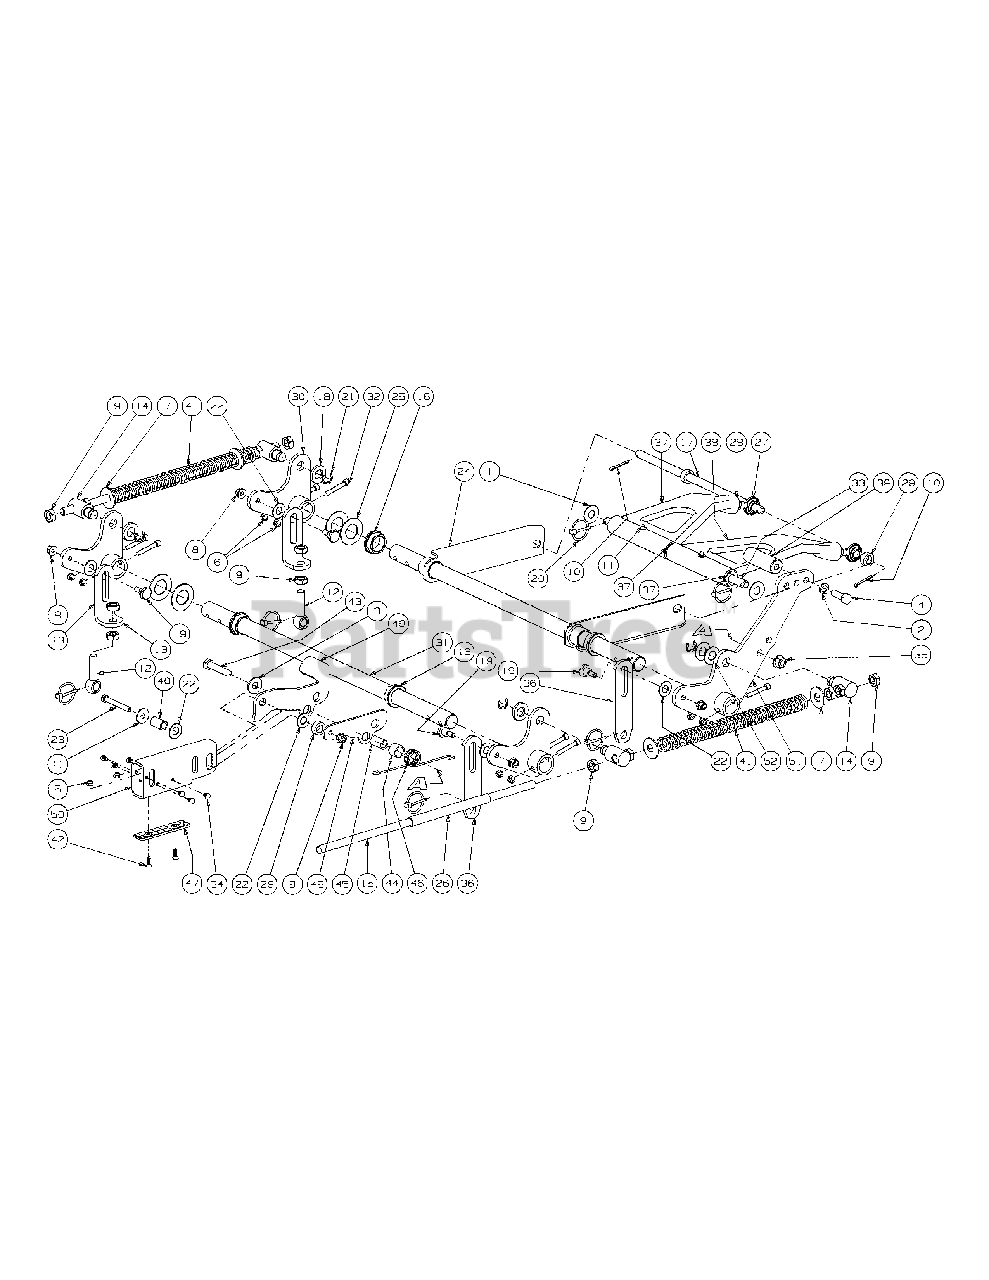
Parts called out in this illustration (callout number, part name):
1	Washer, 1.5 x .655 x .055
2	Lock Washer, 1/2
3	Flat Washer, .536 ID x .930 OD x .05
4	Hex Cap Screw, 1/2-13 x 1.50
5	Lock Nut w/Nylon Insert
6	Nut, 5/16-18, Nylock
7	Flat Washer, 5/8
8	Hex Nut, Flange Lock, 3/8-16
9	Jam Nut, 5/8-11
10	Cotter Pin, 3/16 x 1-1
11	Flat Washer, 1.25 x .411 x .100
12	Eye Bolt, 5/8ID
13	Eye Bolt Mount Link, 5/8 ID
14	Ferule Lift
15	Lift Connector Rod
16	Hex Flange Bearing, 1.25 ID
17	Front Lift Link, Rod Mount
18	Spacer, .812 ID x .268 Lg.
19	Shoulder Screw, 0.625 OD x .437 Lg.
20	Linch Pin, 3/16 Dia.
21	E Clip, 3/4 Dia.
22	Nylon Flat Washer, 5/8
23	HHCS, 3/8-16, 3.00
24	Front Frame Strut Assembly
25	Flat Washer, 1.25 ID
26	Hose, 5/8 ID 13/16 OD, 8" LG
27	Rod End, Male
28	Jam Nut, 5/8-18
29	Spacer, .630 ID x 1.06 OD x .440
30	Bellecrank Weldment Assembly
31	Deck Lift Shaft
32	Socket Head CapScrew, 5/16-18 x 2
33	Lift Link Rod
34	Rivet, 1/4 x 5/8
35	Nut, 1/2-13, FlangeLock
37	Bearing Lift Brace Assembly, Left Hand includes:
37	Grease Fitting
38	Bearing Lift Brace Assembly, Right Hand includes:
38	Grease Fitting
39	Deck Lift Foot Pedal
40	Spacer, .375 ID x .625 OD x 2.20
41	Lift Compression Spring
42	Flat Head Cap Screw, 1/4-20 x .75
43	HHCS, 1/2-13 x 2.50
44	Spacer, .76 ID x 1.0 OD x .75
45	Spacer, .51 ID x .75 OD x 1.240
46	Torsion Spring, .120 Wire x 1.32 OD
47	Lift Wear Plate
49	Lift Link Bracket
50	Lift Tube, 3.0 x 1.5
51	Deck Lift Foot Pedal Weldment
52	Washer, .76 x 1.49 x .06
